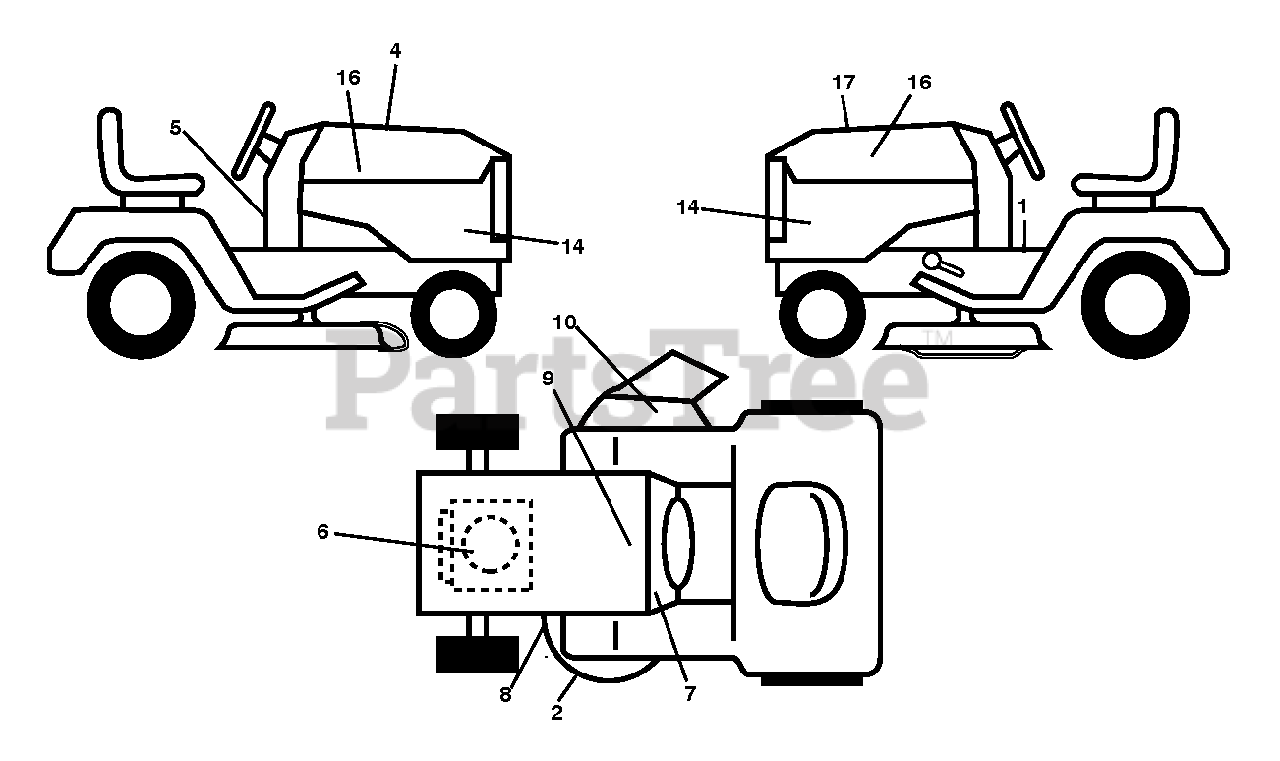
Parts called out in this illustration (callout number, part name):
1	DECAL.WARNING.2007.ENG/FR
2	DECAL.MOWER.SCH.48/54.PREM
4	DECAL.WARNING.CUST.RESP.E85.
5	DCL.WARNING.SPARK.IGNITION.CA
6	DECAL.ENG.BS.ENDUR.24HP.382021
7	DECAL.SNOWFLAKE.MS498.HUSQ
8	DECAL.MOWER.CAUTION.TENSION.AR
9	DECAL BTRY SYMBOLS
10	DECAL, DECK DEFLECTOR, WARNING
14	DECAL.SDPNL.HUSQGT.GTH24V54.RH
16	DECAL.BADGE.170MM.TEXTLOGO.
17	DECAL.RPL.BSM44.ENDUR.TGW.54
